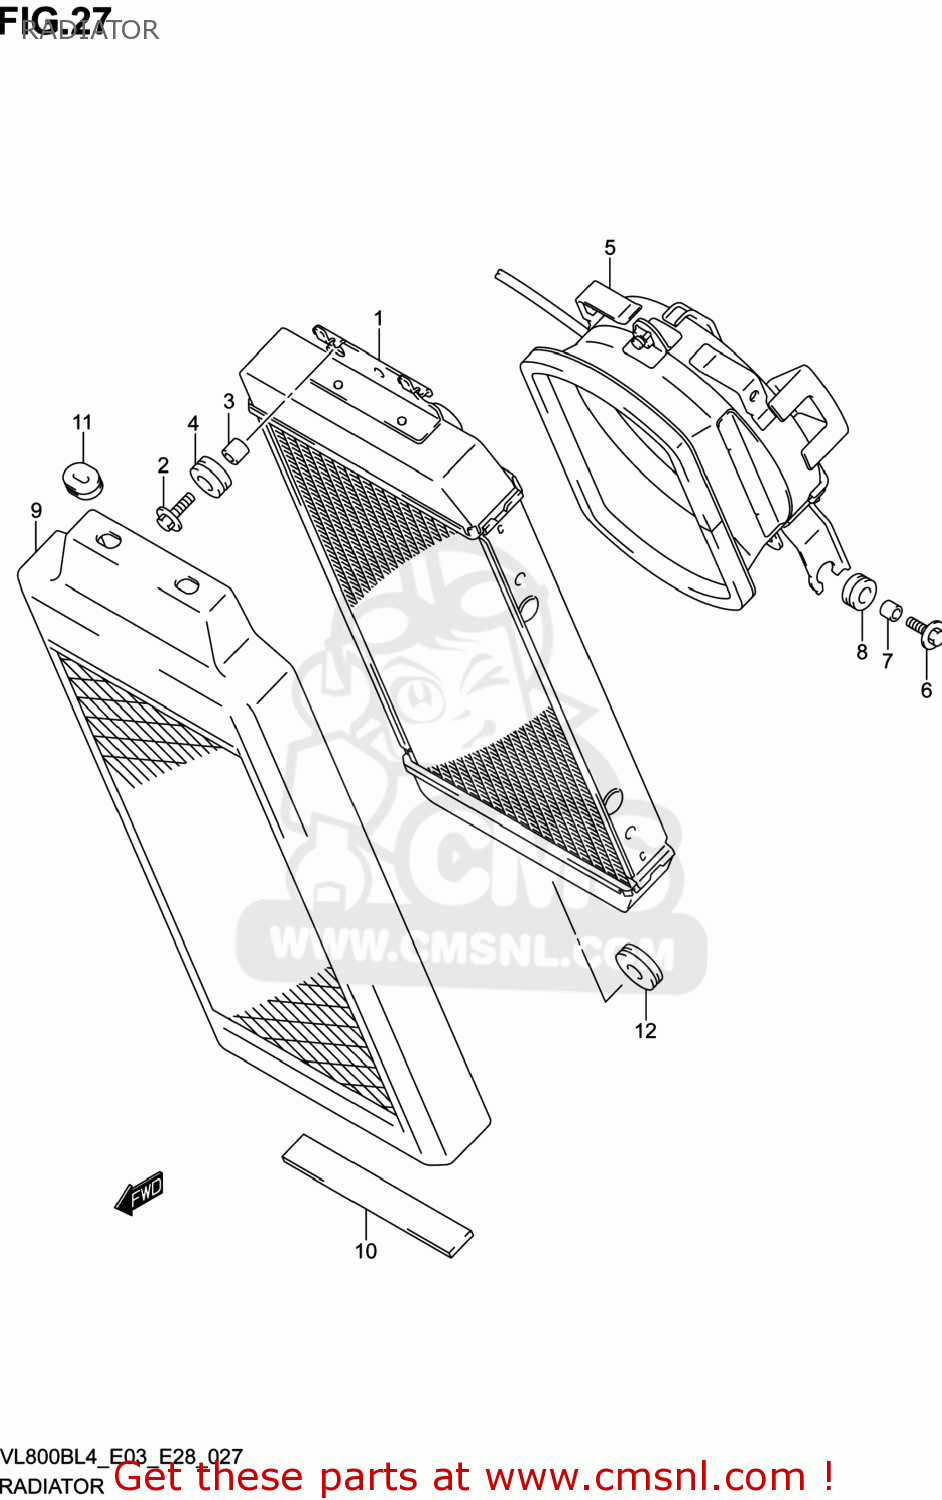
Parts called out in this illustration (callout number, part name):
1	RADIATOR ASSY,WATER
2	BOLT(6X20)
3	SPACER(6.5X10X10)
4	CUSHION
5	FAN ASSY,RADIATOR
6	BOLT(6X20)
7	SPACER(6.5X10X10)
8	CUSHION
9	COVER,RADIATOR
10	CUSHION,RADIATOR COVER INNER
11	CUSHION
12	CUSHION
